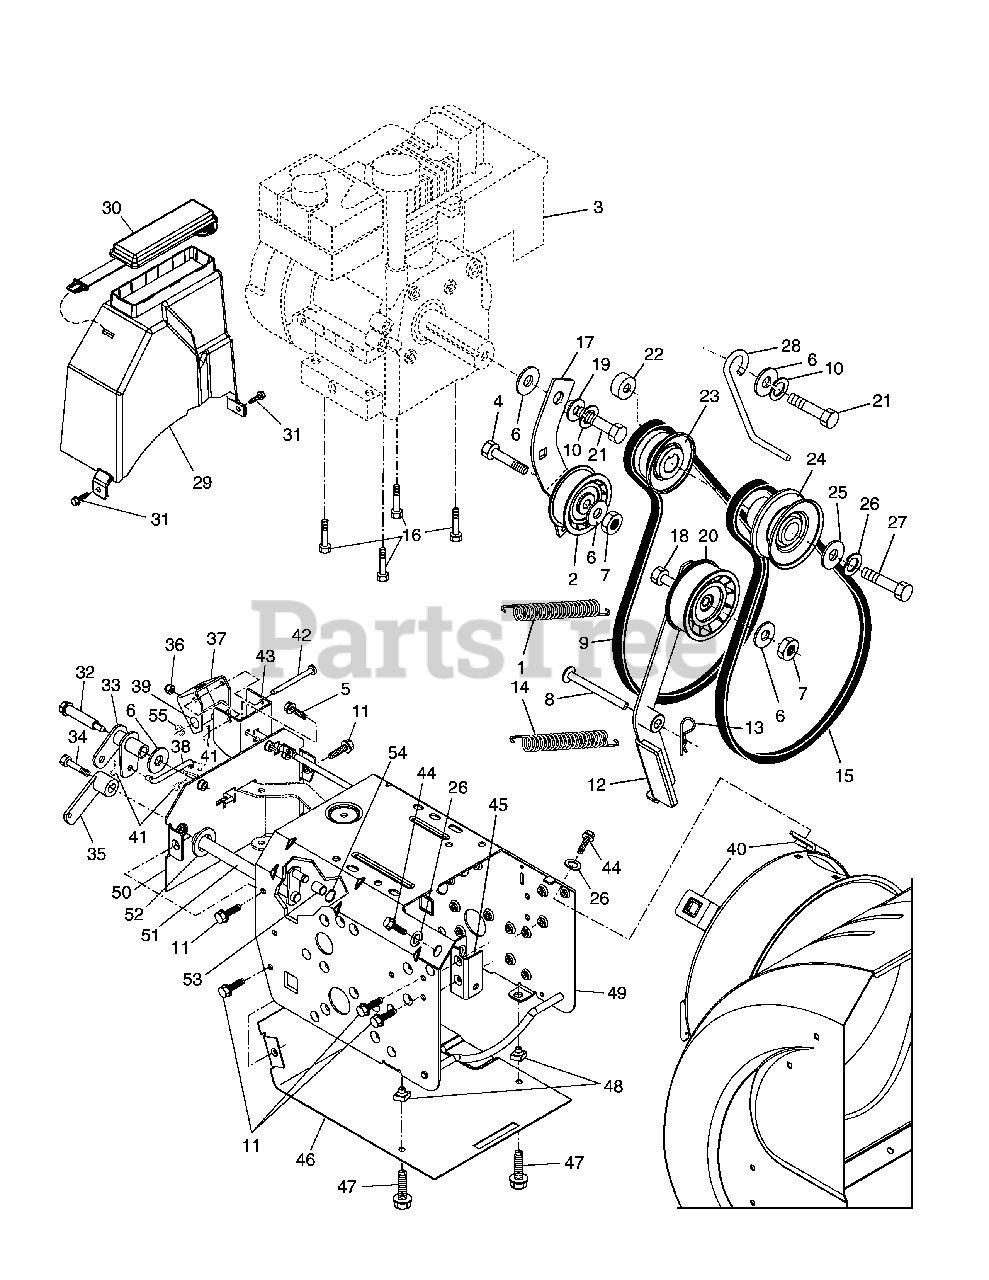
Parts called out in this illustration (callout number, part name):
1	Spring, Traction Idler
2	Pulley, Idler (2-1/4)
4	Screw, Hex Head 5/16-18 x 1-1/4
5	Screw, Hex Washer Head 5/16-18 x 3/4
6	Washer, Flat
7	Nut, Jam, Lock 5/16-18
8	Pin, Idler Pivot
9	V-Belt, Traction Drive
10	Washer, Lock 5/16
11	Screw, Hex Washer Head 5/16-18 x 1/2
12	Impeller Idler Arm Assembly
13	Retainer, Hairpin
14	Spring, Brake
15	V-Belt, Impeller Drive
16	Screw, Hex Head 3/8-16 x 1-1/4
17	Arm, Idler
18	Screw, Hex Head 5/16-18 x 1-1/2
19	Bushing, Idler Pivot
20	Pulley, Idler (2-3/4)
21	Screw, Hex Head 5/16-24 x 1
22	Spacer, Engine Pulley
23	Pulley, Engine, Traction Drive
24	Pulley, Engine, Impeller Drive
25	Washer, Flat 3/8
26	Washer, Lock 3/8
27	Screw, Hex Head 3/8-24 x 1-3/8
28	Guide, Belt
29	Cover, Belt
30	Cover, Toolbox
31	Screw, Hex Head 1/4-20 x 1/2
32	Bolt, Shoulder 5/16-18
33	Bellcrank Shifter
34	Screw, Hex Head 1/4-28 x 3/4
35	Arm, Auger Control
36	Nut, Lock 5/16-18
37	Bellcrank Assembly
38	Link, Speed Control
39	Trunnion, Clutch
40	Nut, Cage 3/8-16
41	Hairpin, Cotter 3/32 x 1/2
42	Pin, Bellcrank
43	Bracket, Bellcrank
44	Screw, Hex Head 3/8-16 x 1-1/2
45	Pivot Bracket, Impeller Idler Arm
46	Pan, Frame Bottom
47	Screw, Hex Head 5/16-18 x 3/4
48	Nut, Speed 5/16-18
49	Frame Assembly
50	Plate, Frame End
51	Shaft, Auger Control
52	Washer, Hardened
53	Roller
54	Ring, Crescent
